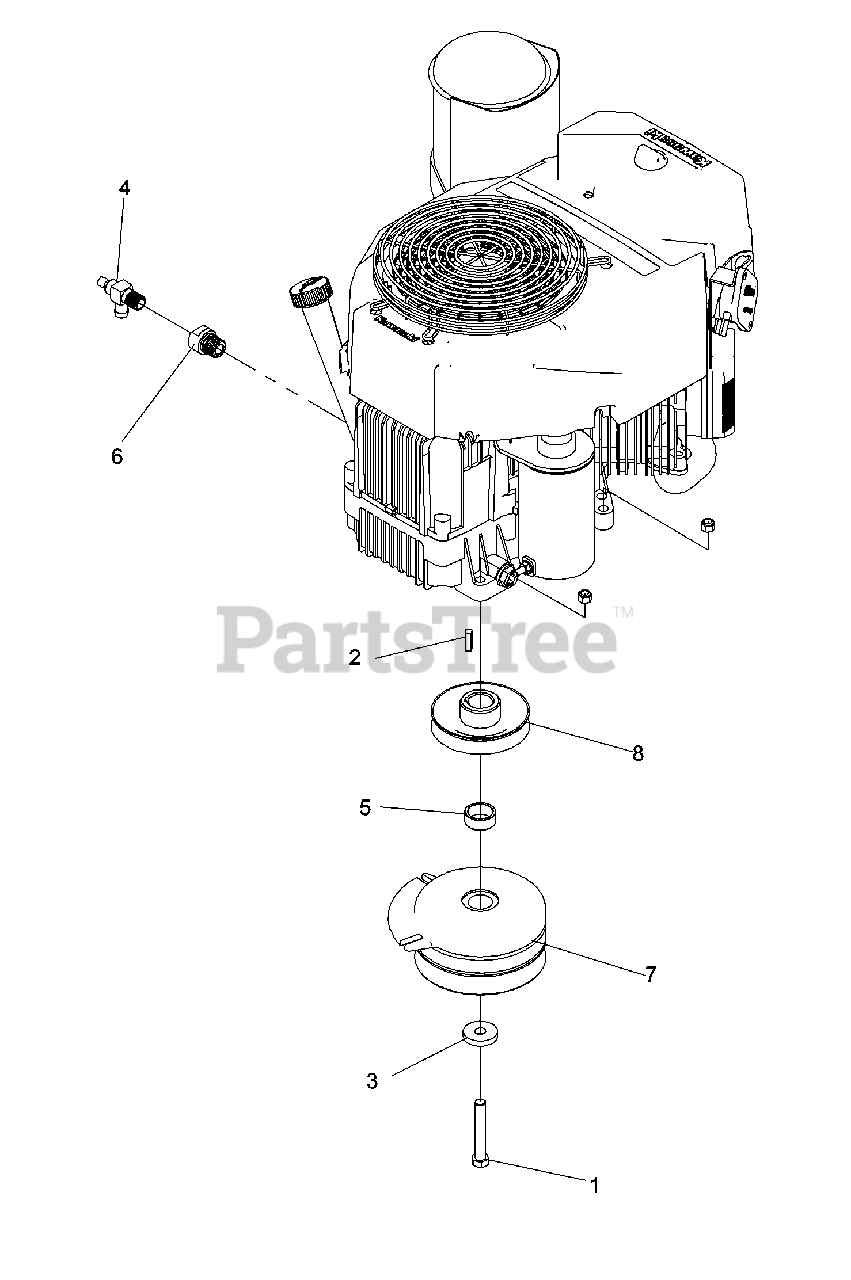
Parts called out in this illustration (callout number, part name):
1	HCS 7/16-20 X 2-3/4
2	KEY - 1/4 X .88
3	WASHER .43X1.38X.25
4	OIL DRAIN
5	HUB BEARING SPACER
6	ADAPTER, OIL DRAIN
8	DRIVE PULLEY-ENGINE
